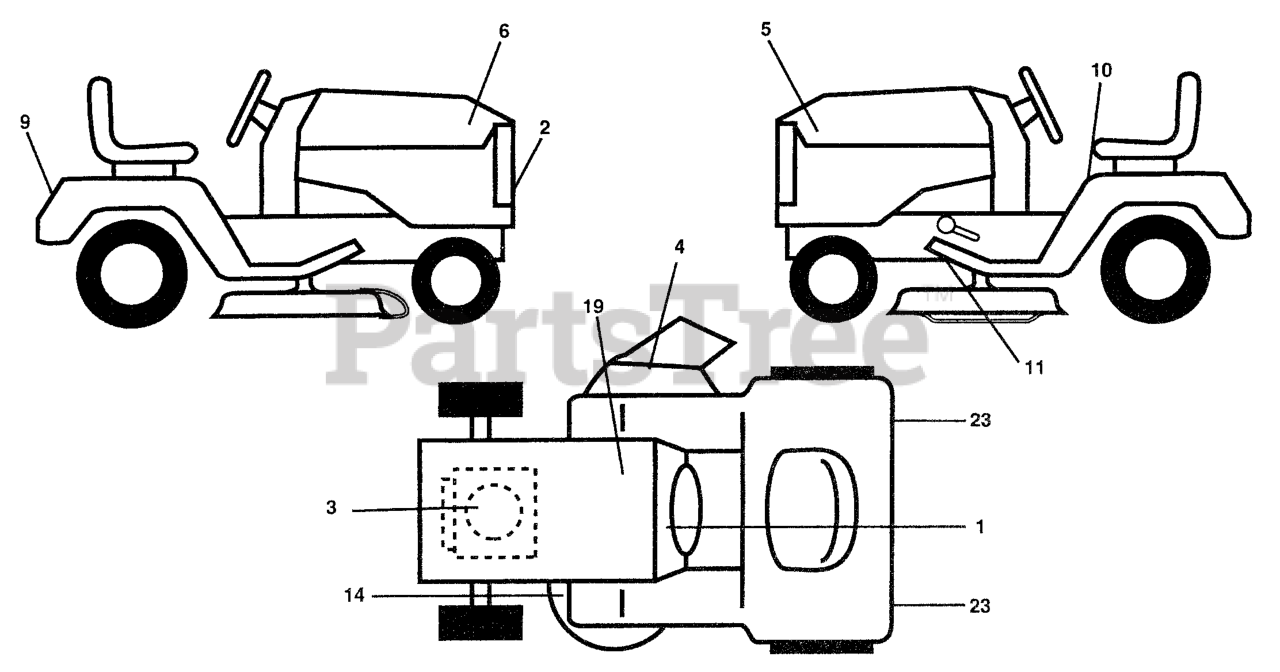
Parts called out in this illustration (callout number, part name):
2	DECAL.GRILLE.HUSQ
3	DECAL, KOHLER
4	DECAL WARNING (ENGLISH/FRENCH)
5	DECAL HOOD LH GT200
6	DECAL HOOD RH GT200
9	DECAL FENDER HUSQ
10	DECAL CAUTION
19	DECAL, BATTERY DANGER
23	REFLECTOR-TAIL YT
